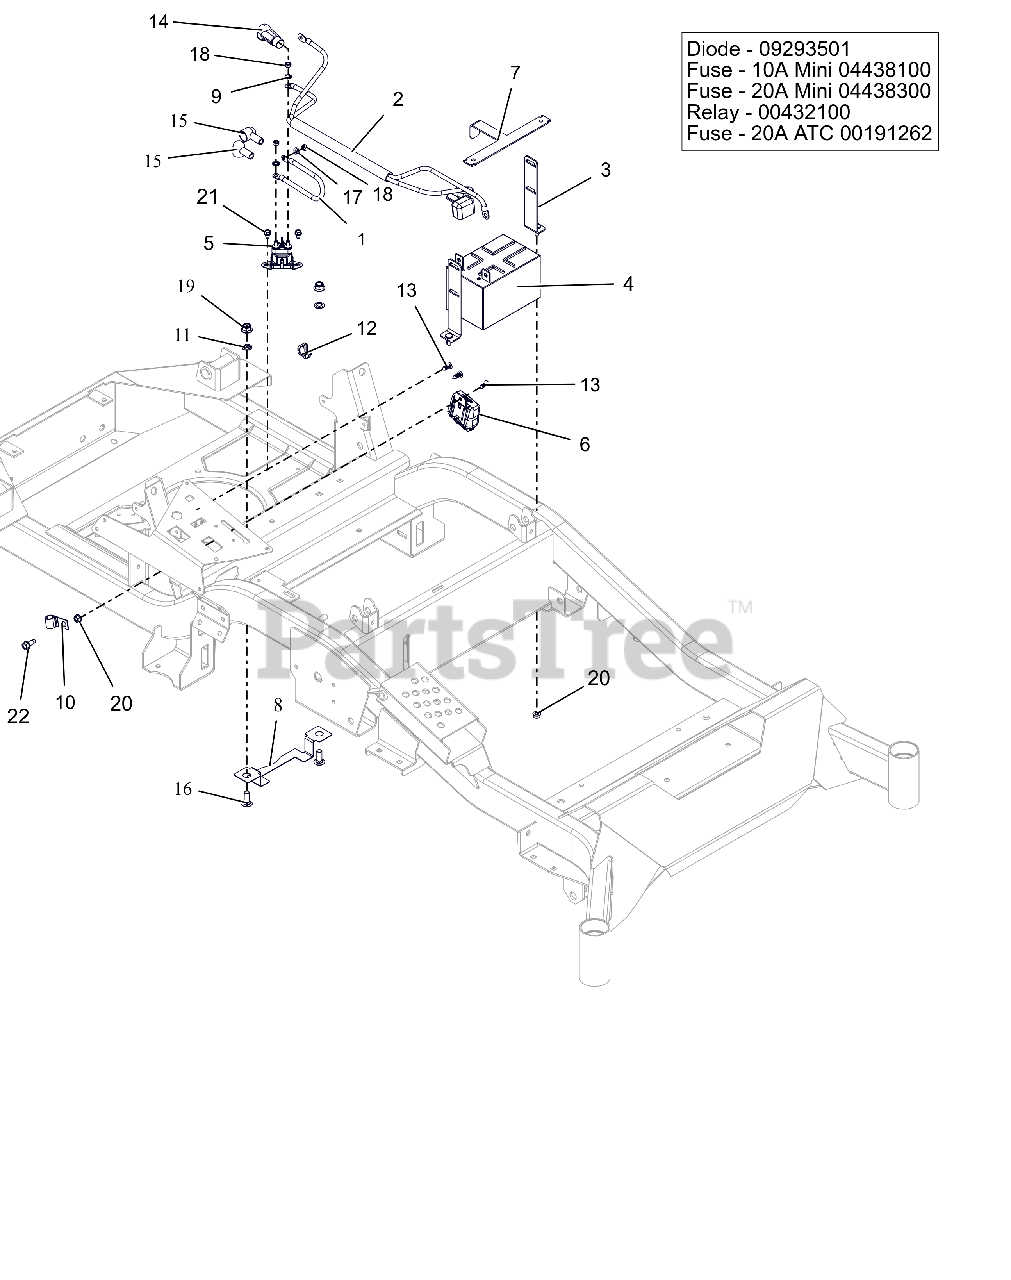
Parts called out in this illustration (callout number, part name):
1	CABLE, POS W/(2)1/4 RING 9.0LG
2	HARNESS, BATTERY HD
3	WMT,BATTERY MOUNT HOLD DOWN
4	BATTERY, 12V 12A-190CCA
5	SOLENOID, STARTER (SEALED)
6	HARNESS, WIRE
6	DIODE, CONNECTOR SHELL
6	FUSE,10 AMP MINI-ATC
6	FUSE,20 AMP MINI ATC
6	RELAY,SEALED W/DIODE
6	FUSE, 20 AMP BLADE S/O
7	BRKT, BATTERY TIE DOWN
8	GUARD, ELECTRICAL HARNESS
9	@WSHR-LK-EXT.262X.502X.026YWZC
10	J-CLAMP
11	NUT-PUSH .38 DIA. PAL ZINC
12	CABLE TIE W/ TREE (.25 HOLE)
13	RIVET, .25 NYLON PANEL
14	BOOT, .65ID POS
15	BOOT, EYELET TERMINAL
16	@BLT-RDHDSQNK .38-16X1.00 G5YZ
17	@WSHR-LK .31X.078 REG YWZC
18	NUT-HEX M6X1.0 YWZC
19	@NUT-LK-NYL-FLG .38-16 YWZC
20	@NUT-LK-TOP-FLG .25-20 YWZC
21	@SCR-TAP .25-20X.37 HWH YWZ TR
22	@SCR-TAP .31-18X.75 HWH TR YWZ
